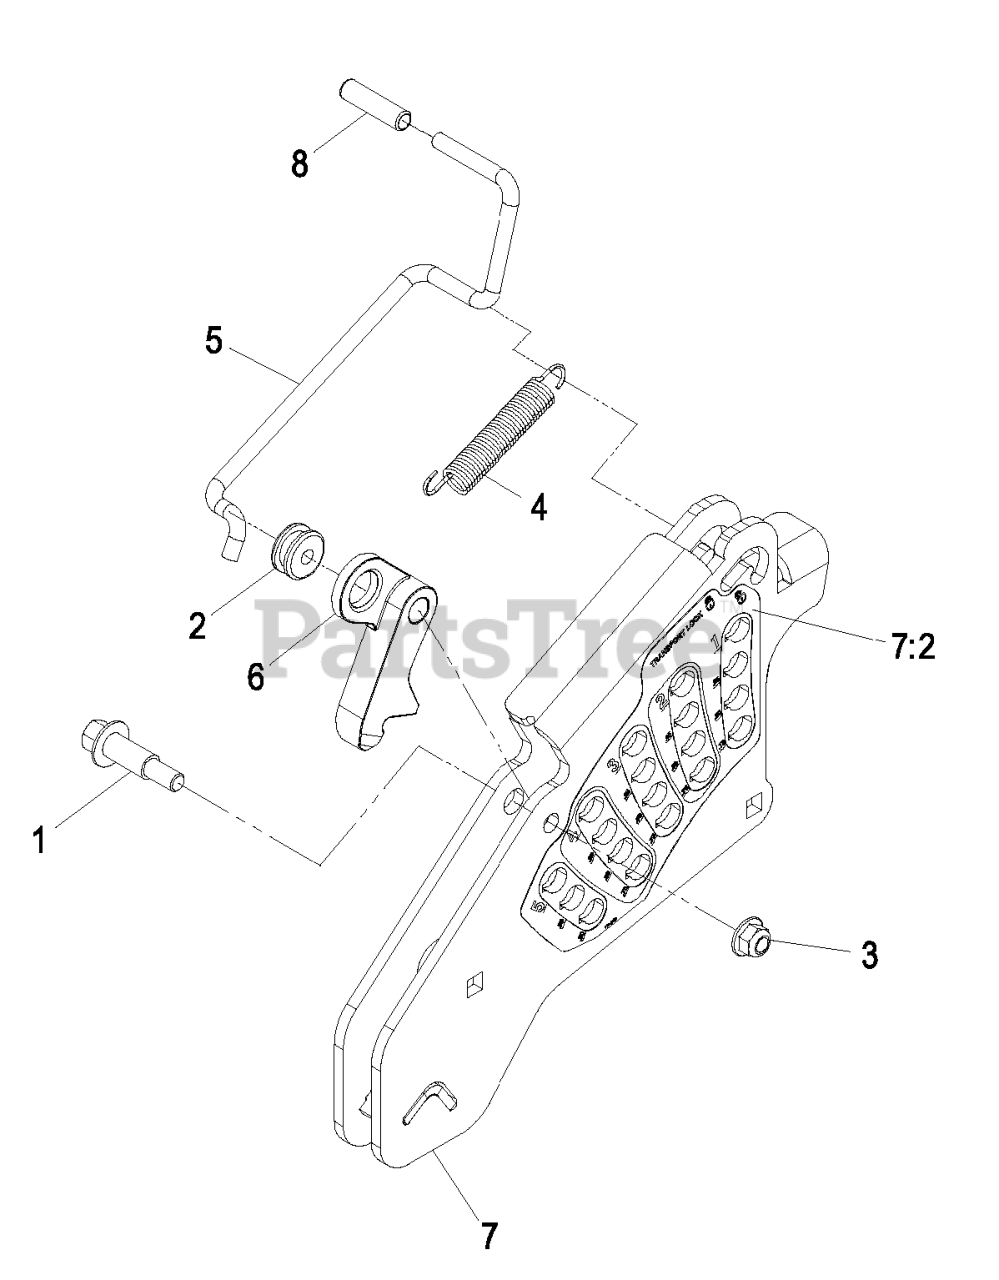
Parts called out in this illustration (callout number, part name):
1	BOLT-SHOULDER
2	GROMMET
3	NUT-HF, NI
4	SPRING-EXTENSION
5	ROD-LOCK, TRANSPORT
6	PAWL-TRANSPORT, HOC
7	HOC PLATE ASM
7:2	DECAL-HOC
8	GRIP-LEVER
